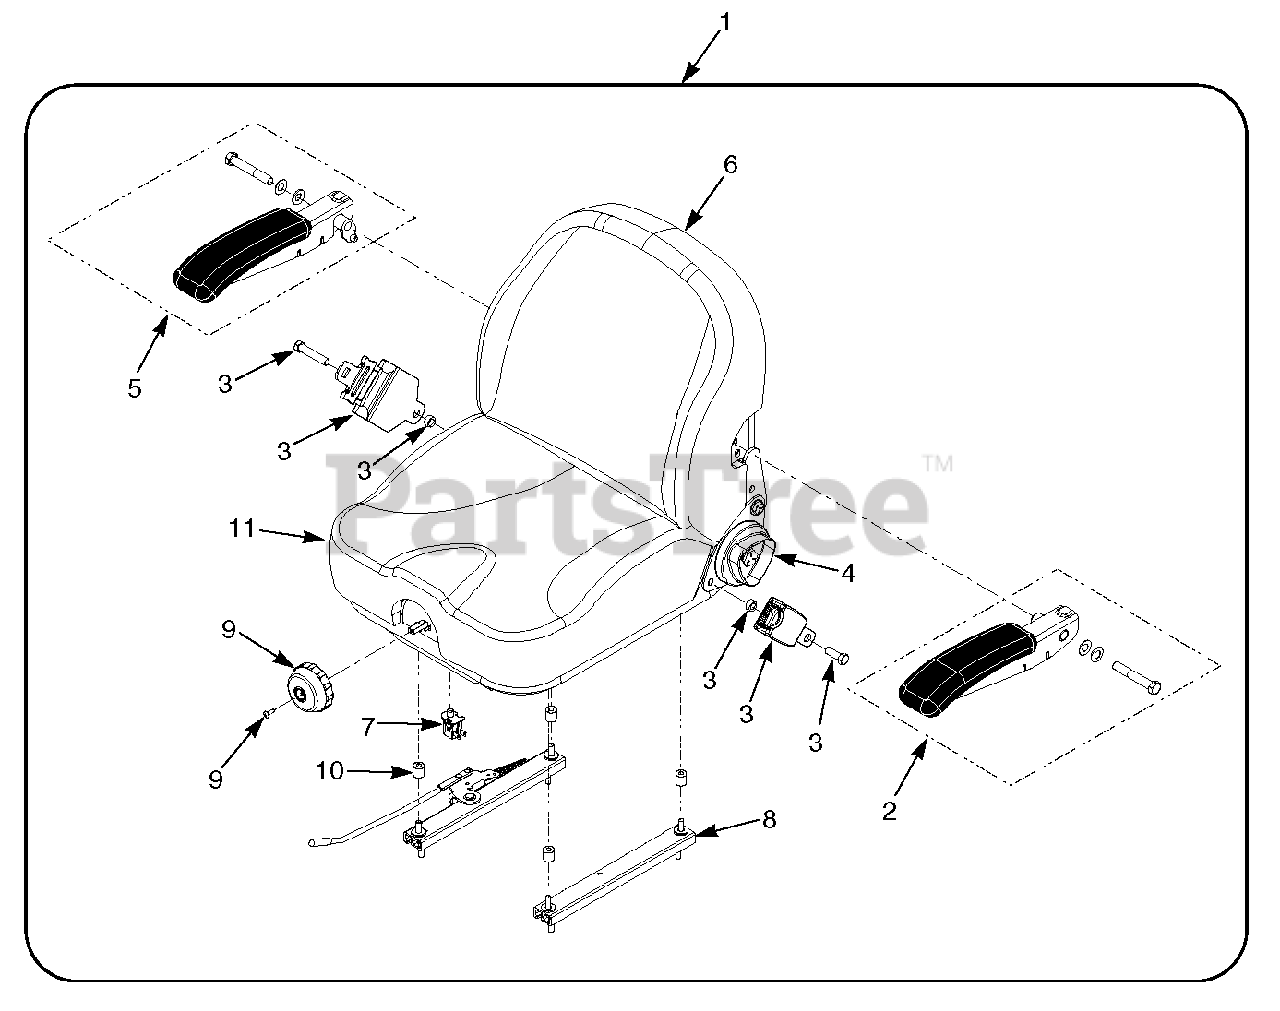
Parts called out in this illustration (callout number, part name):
1	Suspension Seat Assembly w/seat belt
2	Armrest Kit, LH
3	Seat Belt Kit
4	Recliner Knob Kit
5	Armrest Kit, RH
6	Back Cover
7	Seat Switch
8	Track Kit
9	Suspension Knob Kit
10	Spacer
11	Seat Cushion Cover
